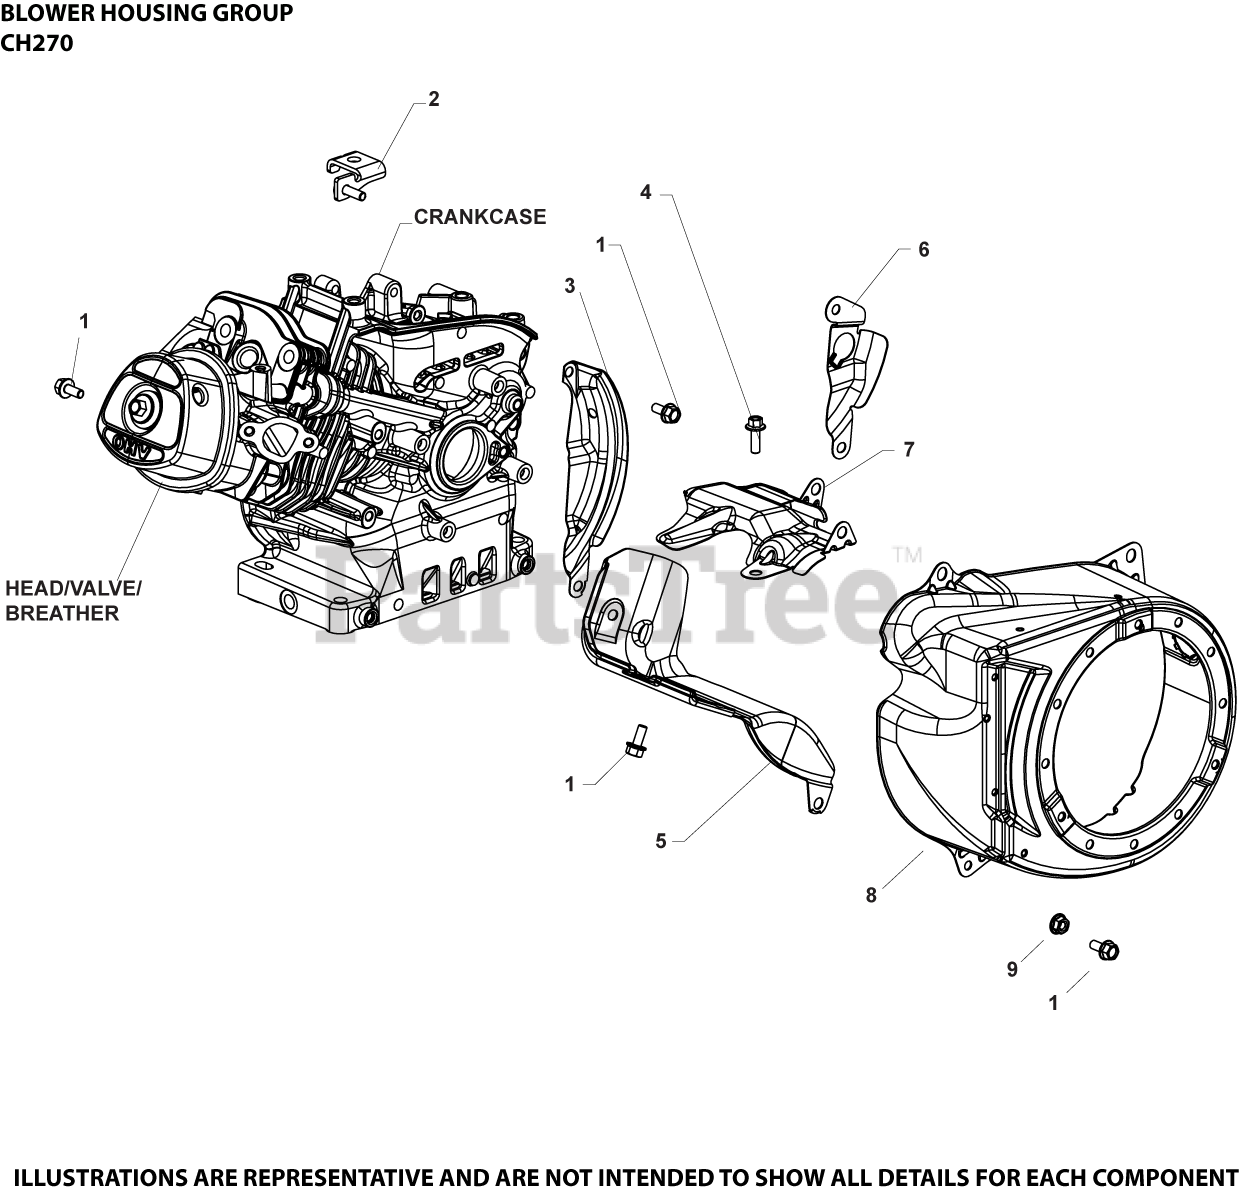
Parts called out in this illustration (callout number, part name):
1	SCREW, HEX FLANGE (M6)-USE 25 086 433-S
3	SHIELD, FLYWHEEL
4	SCREW, M6 X18
5	SHIELD, CYLINDER HEAD
7	SHIELD, UPPER HEAT
8	HOUSING, BLOWER ASSEMBLY
9	NUT, HEX FLANGE (M6) - USE 14 100 16-S
